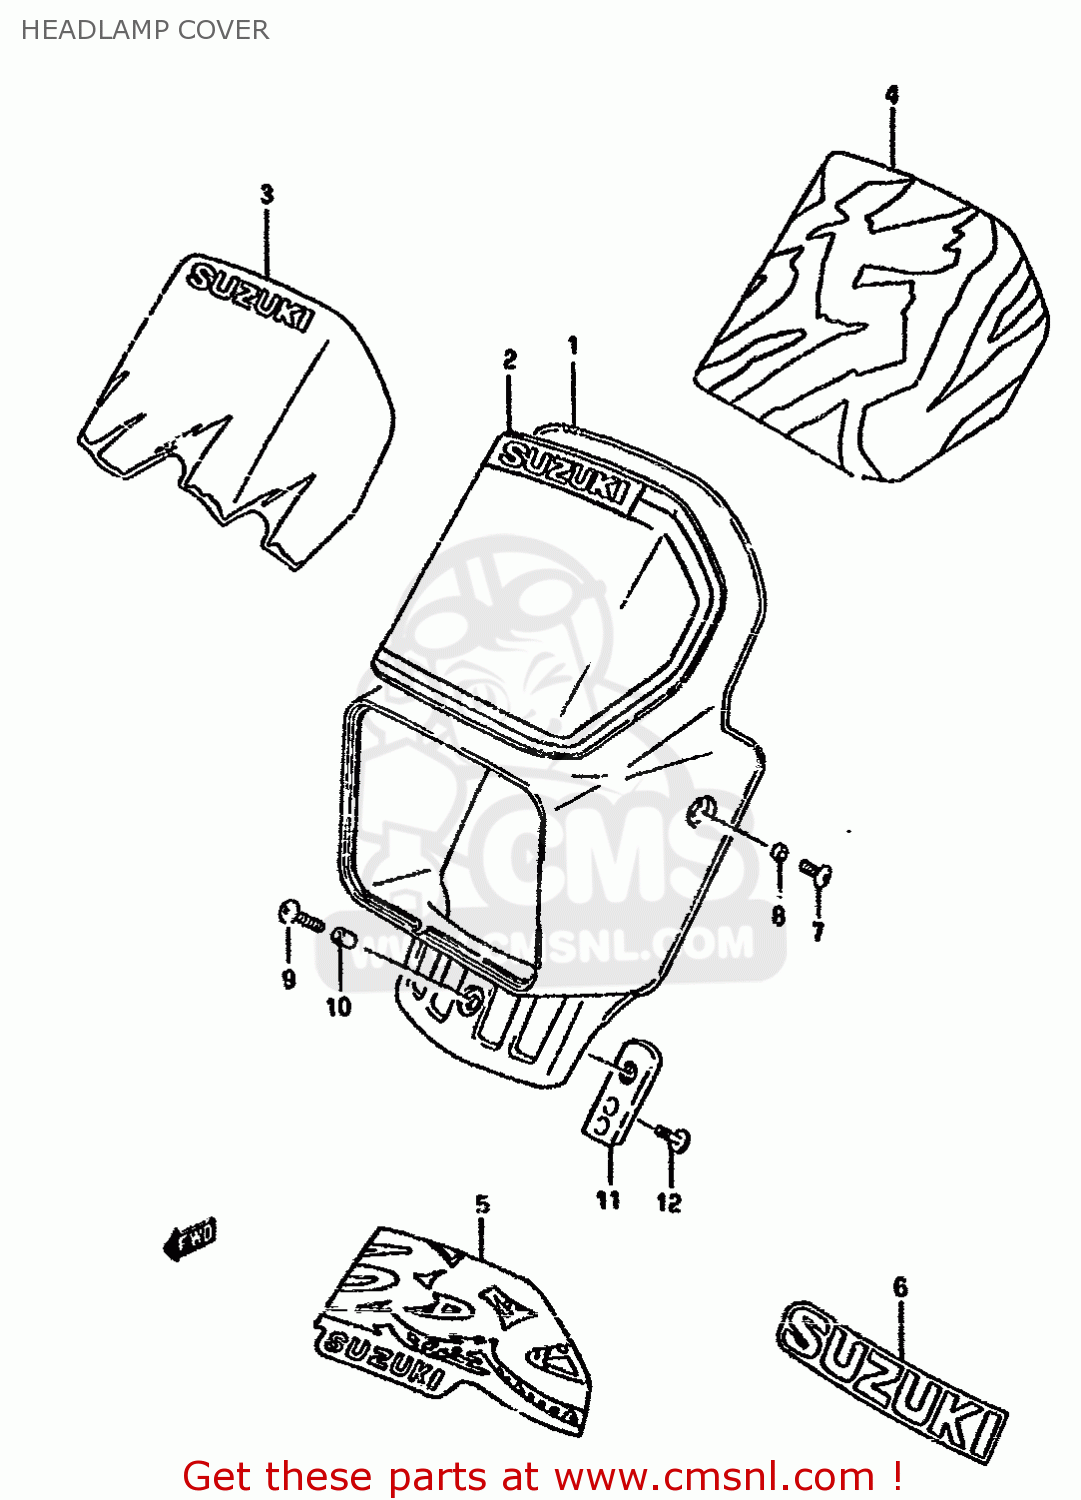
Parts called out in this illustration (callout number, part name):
1	COVER,HEADLAMP
2	TAPE,HEADLAMP COVER
3	TAPE,COVER
4	TAPE,COVER
5	EMBLEM,COVER
6	EMBLEM,HEADLAMP COVER
7	SCREW 6X12
8	SPACER (6.1X8X3.5)
9	SCREW
10	SPACER (6.1X8X12)
11	PLATE,HEADLAMP COVER
12	SCREW
